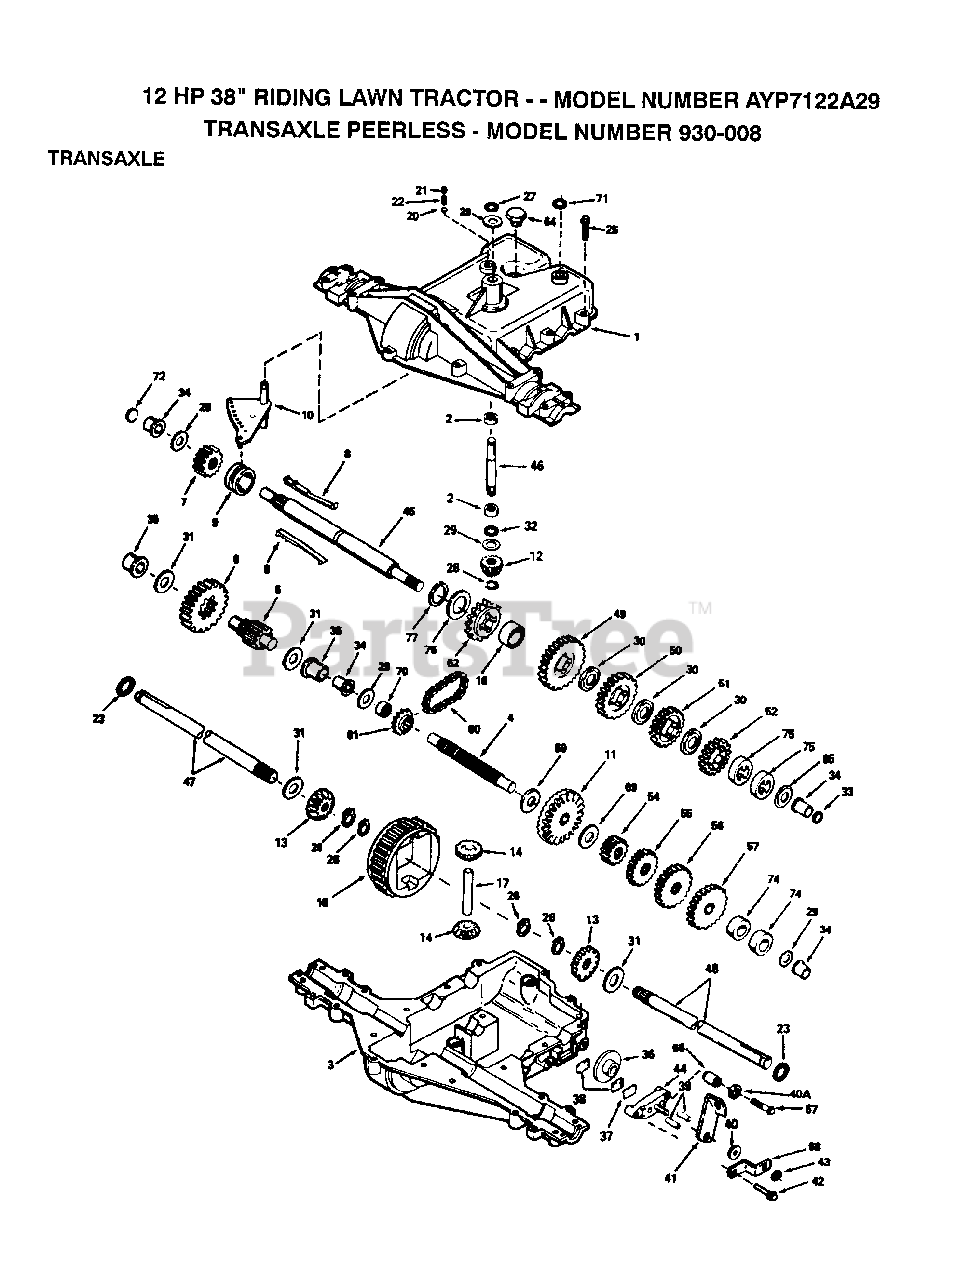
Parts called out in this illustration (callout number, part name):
1	COVER, TRANSAXLE
2	BEARING, NEEDLE
3	CASE, TRANSAXLE
4	SHAFT, COUNTER
5	SHAFT, PINION ASSEMBLY, OUTPUT
6	GEAR, OUTPUT
7	GEAR, SPUR, 15 TEETH
9	COLLAR, SHIFTER
10	ROD & FORK ASSY, SHIFT
11	GEAR, BEVEL, 42 TEETH
12	BEVEL PINION, INPUT
13	GEAR, BEVEL
14	GEAR, BEVEL, PINION
18	SPACER, NEUTRAL
20	BALL STEEL, 5/16" DIA.
21	SCREW, 3/8-16 X 3/8"
25	SCREW, 1/4-20 X 1-1/4
26	RING RETAINER
27	RING, RETAINER
28	RETAINING RING
29	WASHER THRUST
30	WASHER THRUST
33	SEAL, SQUARE CUT
34	BUSHING, FLANGED
35	BUSHING, FLANGED
36	DISK, BRAKE
37	PLATE BRAKE PAD
40	WASHER, FLAT
40A	WASHER FLAT
41	LEVER BRAKE
42	SCREW, 1/4-20 X 1-1/4
43	LOCKNUT 5/16-24
44	HOLDER BRAKE PAD
45	SHAFT, BRAKE, 4 KEYED
46	SHAFT, INPUT
49	GEAR, SPUR, 37 TEETH
50	GEAR, SPUR, 30 TEETH
51	GEAR, SPUR, 25 TEETH
52	GEAR, SPUR, 19 TEETH
54	GEAR, SPUR, 12 TEETH
55	GEAR, SPUR, 20 TEETH
56	GEAR, SPUR, 25 TEETH
57	GEAR, SPUR, 31 TEETH
60	CHAIN, ROLLER
61	SPROCKET 9T
62	SPROCKET 18T (REV)
64	PLUG, THRDED, 9/16-18
67	SCREW FLNG HEX 1/4-20 X 2-1/4
68	BRKT BRAKE LEVER
69	WASHER THRUST
71	SEAL SQUARE CUT
76	WASHER, THRUST
77	RING, RETAINING
